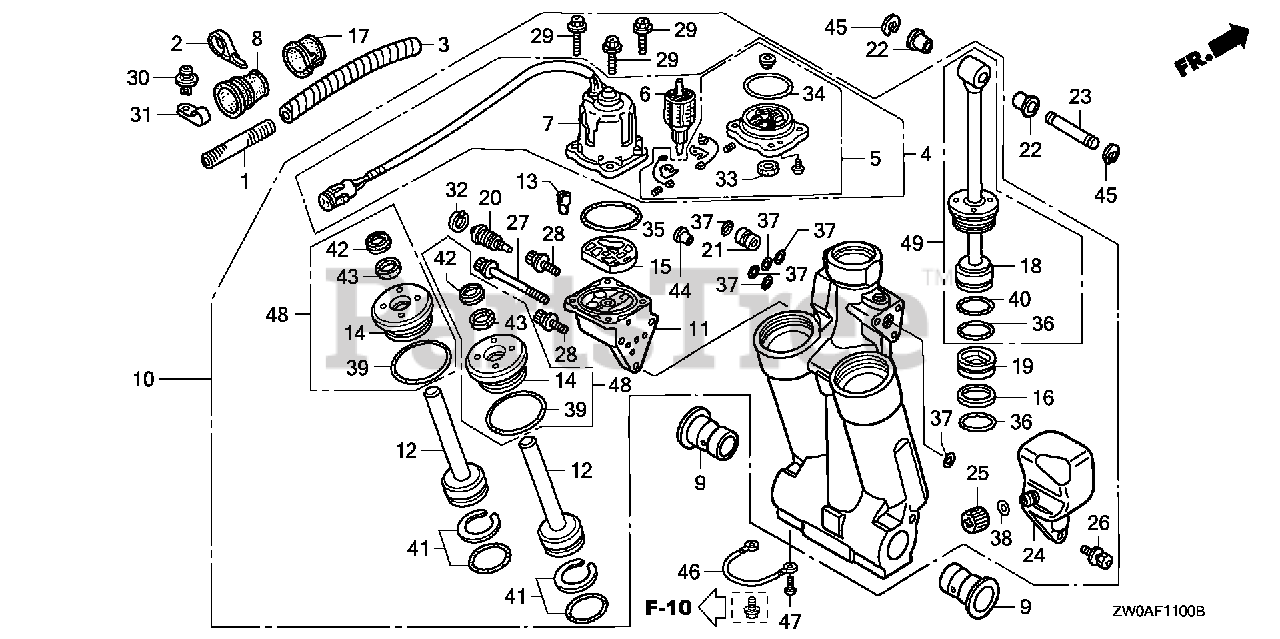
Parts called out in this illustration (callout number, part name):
1	TUBE, CORRUGATE (10MM)
2	BAND (BLACK 3.5X140)
3	TUBE, SPIRAL (12X14.6)
4	MOTOR ASSY., POWER TILT
5	BRACKET ASSY.
6	ARMATURE
7	YOKE ASSY.
8	GROMMET, CASE (LOWER) (C)
9	BUSH, SWIVEL CASE
10	TRIM-TILT ASSY., POWER
11	PUMP ASSY.
12	ROD, PISTON (B)
13	JOINT, DRIVE
16	RING, BACK-UP
17	BUSH, MOTOR CODE
18	ROD, PISTON
19	PISTON, FREE
20	VALVE, MANUAL
21	VALVE, RESERVOIR
22	BUSH, CYLINDER (LOWER)
23	PIN, CYLINDER (UPPER)
24	TANK, OIL
25	CAP, OIL TANK
26	BOLT, RECESSED
27	BOLT A, SOCKET
28	BOLT B, SOCKET
29	BOLT, HEX.
30	SCREW, RIVET (5X10)
31	CLIP (10.7MM)
32	CIRCLIP (INNER)
34	O-RING
37	O-RING
38	O-RING
41	O-RING SET
42	SEAL, WATER
44	COLLAR, ORIFICE
45	E-RING (15MM)
48	GUIDE, ROD
49	ROD, PISTON
